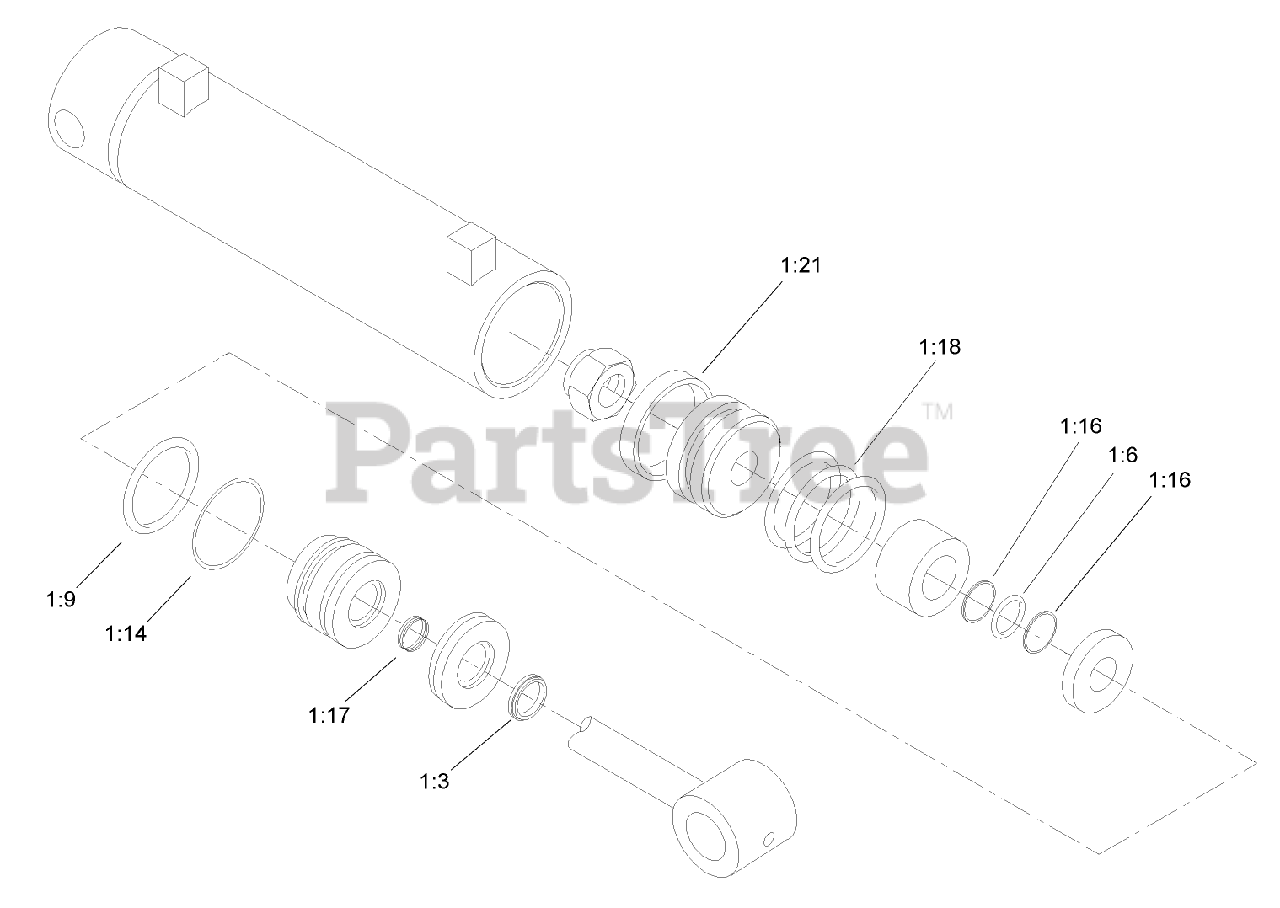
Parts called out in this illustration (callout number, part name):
1	CYLINDER SEAL KIT
1:3	Seal-Wiper
1:6	Seal-Dust
1:9	Seal-Dust
1:14	RING-BACKUP
1:16	RING-BACKUP
1:17	PACKING ASSEMBLY
1:18	PACKING ASSEMBLY
1:21	RING-WEAR
